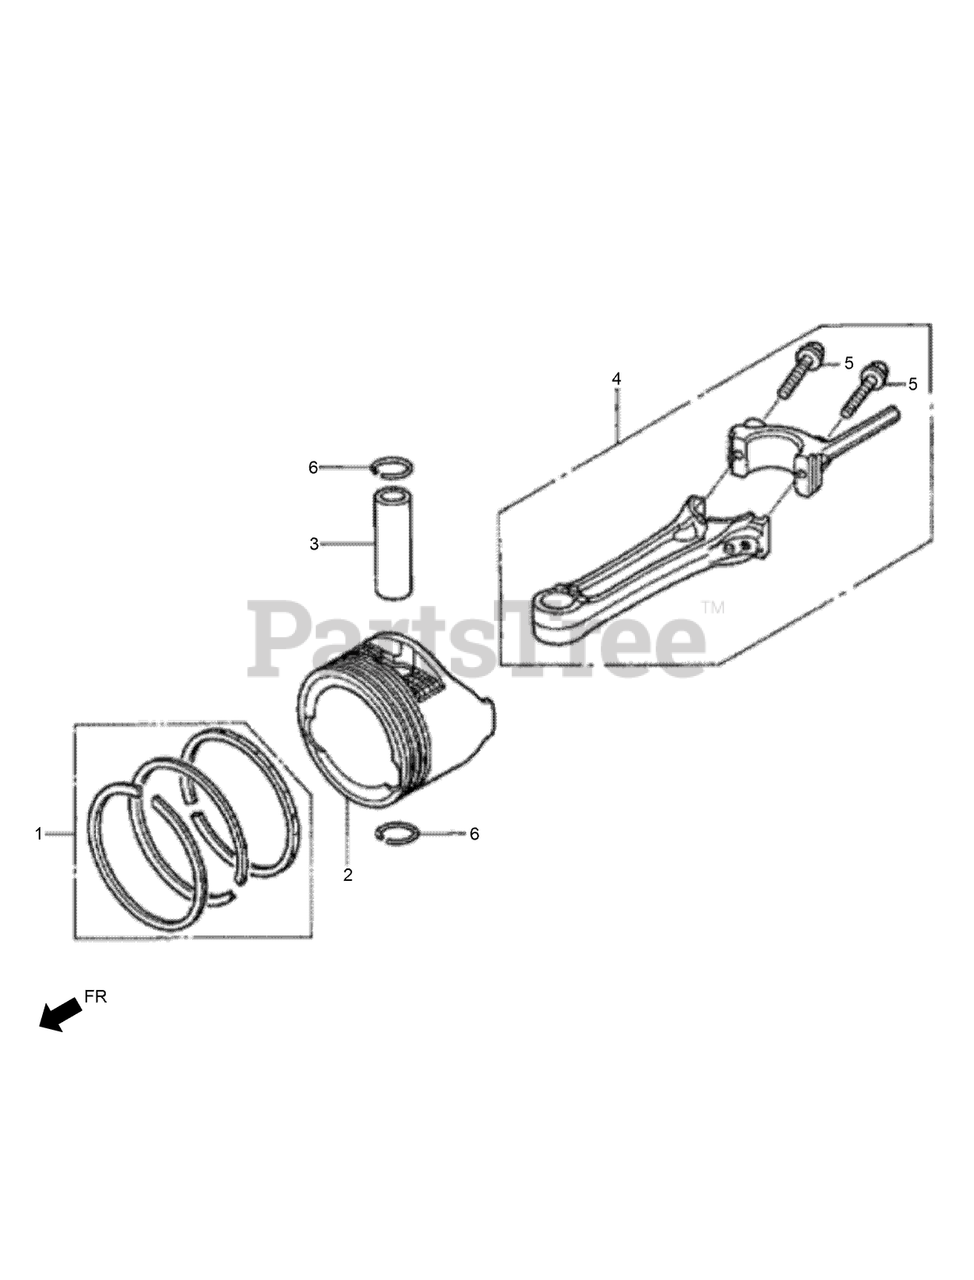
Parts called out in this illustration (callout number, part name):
1	RING SET-PISTON
1	RING SET-PISTON (STD)
2	PISTON
3	PIN-PISTON
4	ROD ASM-CONNECTING
5	BOLT-CONNECTING ROD
6	CLIP-PISTON PIN-13MM
